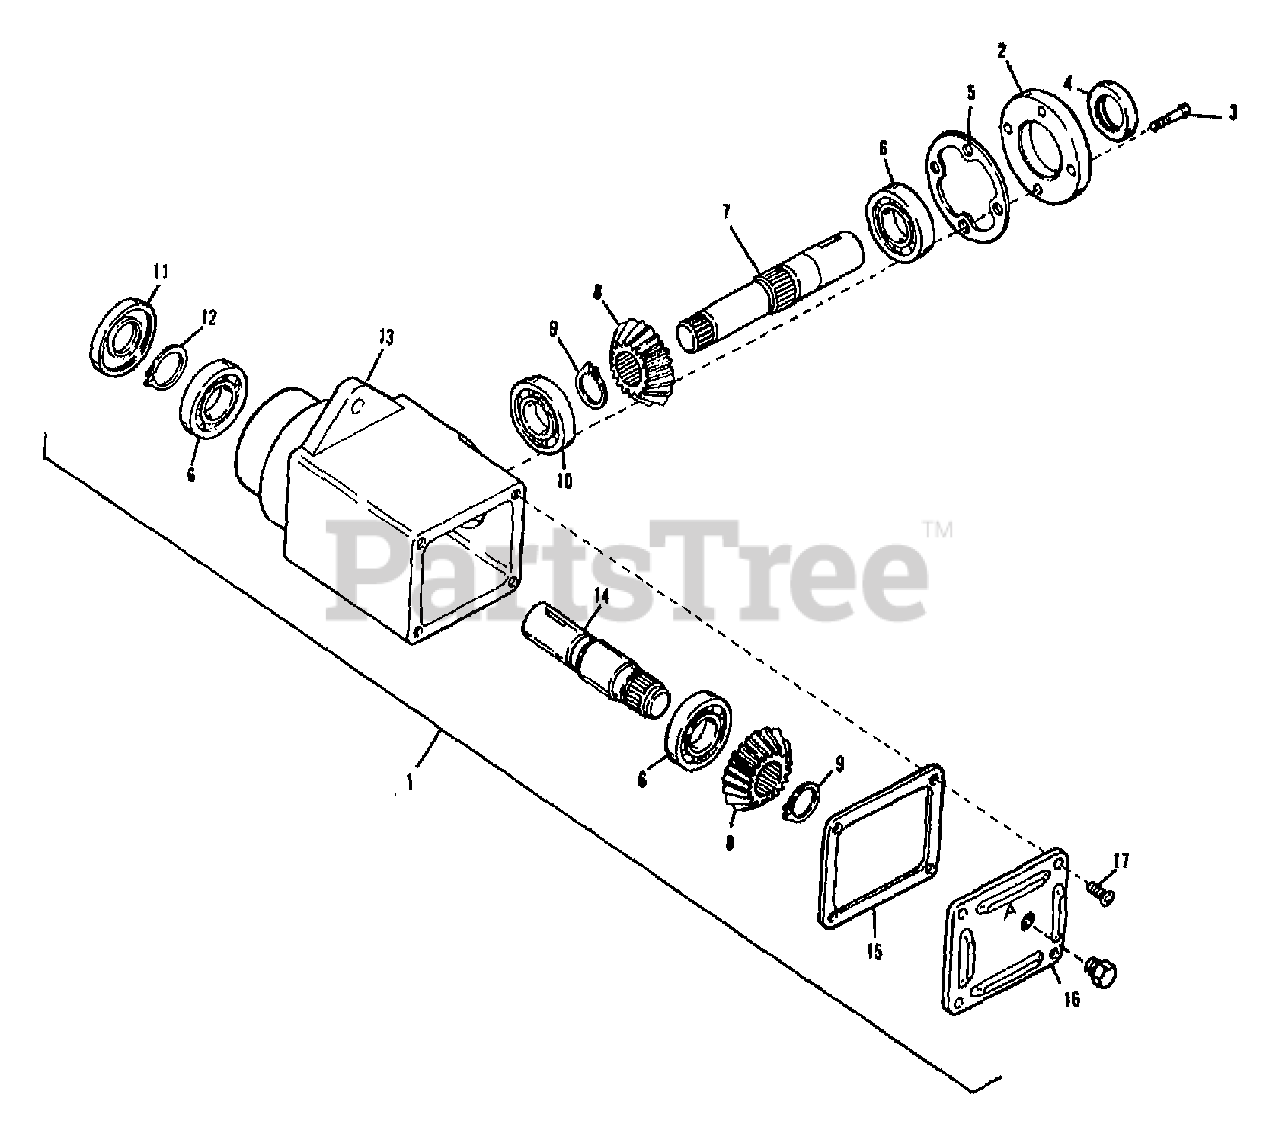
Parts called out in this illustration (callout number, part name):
1	HEAD ASSY
2	CAP & SEAL
4	OIL SEAL
6	BALL BEARING
7	INPUT SHAFT
8	MITER GEAR
9	RET RING
10	BALL BEARING
11	OIL SEAL
12	RET RING
14	OUTPUT SHAFT
15	GASKET
